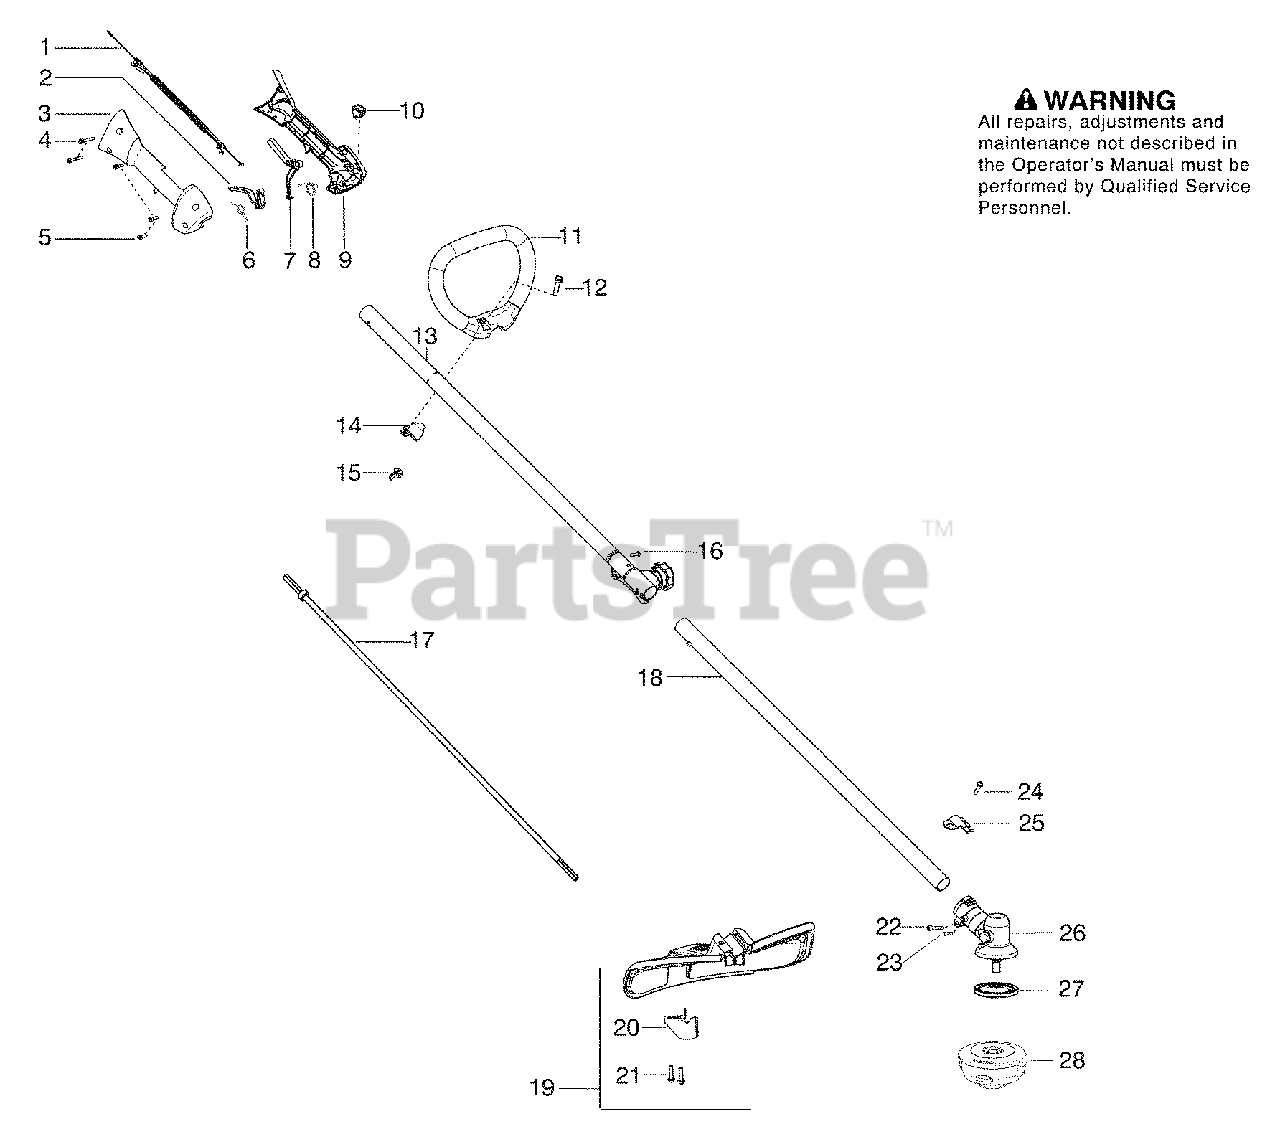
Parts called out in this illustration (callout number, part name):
1	Assy-Cable/Wire Harness
3	Housing-Throttle (RH)
6	Spring-Trigger
7	Lockout-Throttle
8	Spring-Lockout
9	Housing-Throttle (LH)
10	Kit-Switch
11	Handle - Assist
13	Kit-Driveshaft Upper
14	Clamp - Handle Assist
15	Wingnut
18	Kit-Lower Shaft
19	Kit-Shield
20	Limiter - Line
25	Bracket-Shield
26	Assy-Gearbox
27	Driver Disc
28	Assy-T25 Cutting Head
